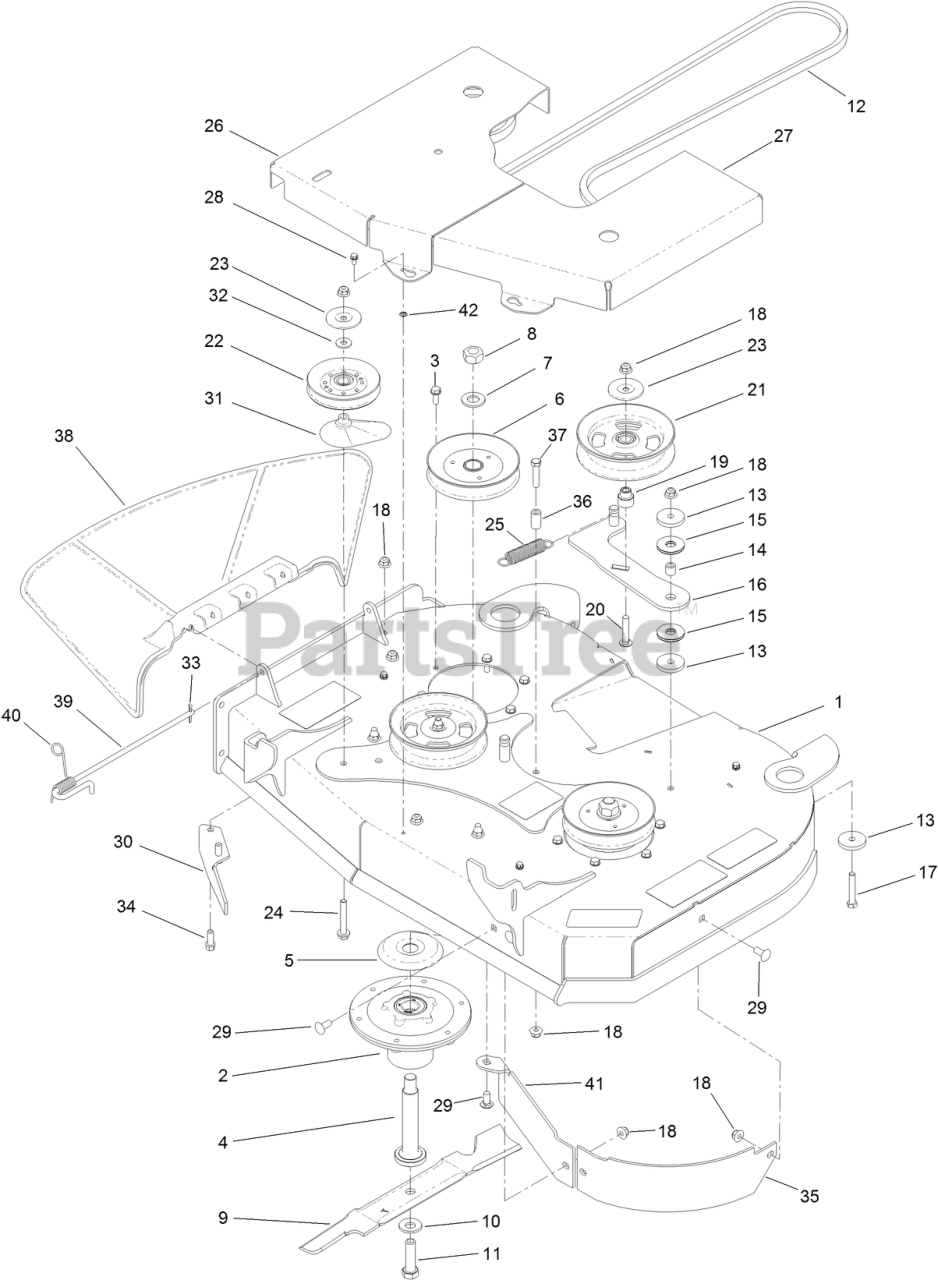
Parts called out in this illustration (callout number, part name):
1	36" DECK ASM-SERVICE
2	SPINDLE ASM
3	SCREW-TAPTITE
4	SHAFT-SPINDLE
5	SHIELD-BEARING
6	PULLEY
7	WASHER
8	NUT-HEX
9	BLADE - HI FLOW, 18.00 IN
10	WASHER-BELLEVILLE
11	SCREW-BLADE
12	BELT-V
13	WASHER-PLAIN
14	BUSHING-IDLER
15	WASHER-FRICTION, COMPOSITE
16	IDLER ARM ASM
17	SCREW-HH
18	NUT-HF, NI
19	BUSHING-IDLER
20	SCREW-CARR
21	PULLEY-IDLER, FLAT
22	IDLER - V 4.13 EOD-A
23	SHIELD-DUST
24	SCREW-HHF
25	SPRING-EXTENSION
26	COVER-DECK
27	COVER-DECK
28	SCREW-HWH
29	SCREW-CARR
30	BAFFLE-DISCHARGE
31	SPACER-PULLEY
32	WASHER-HARDENED
33	PIN-COTTER
36	SPACER-FENDER
37	SCREW-HH
38	DEFLECTOR-DISCHARGE
39	PIN-CHUTE
40	SPRING-TORSION
41	PLATE-DEFLECTOR
42	NUT-RETAINING
